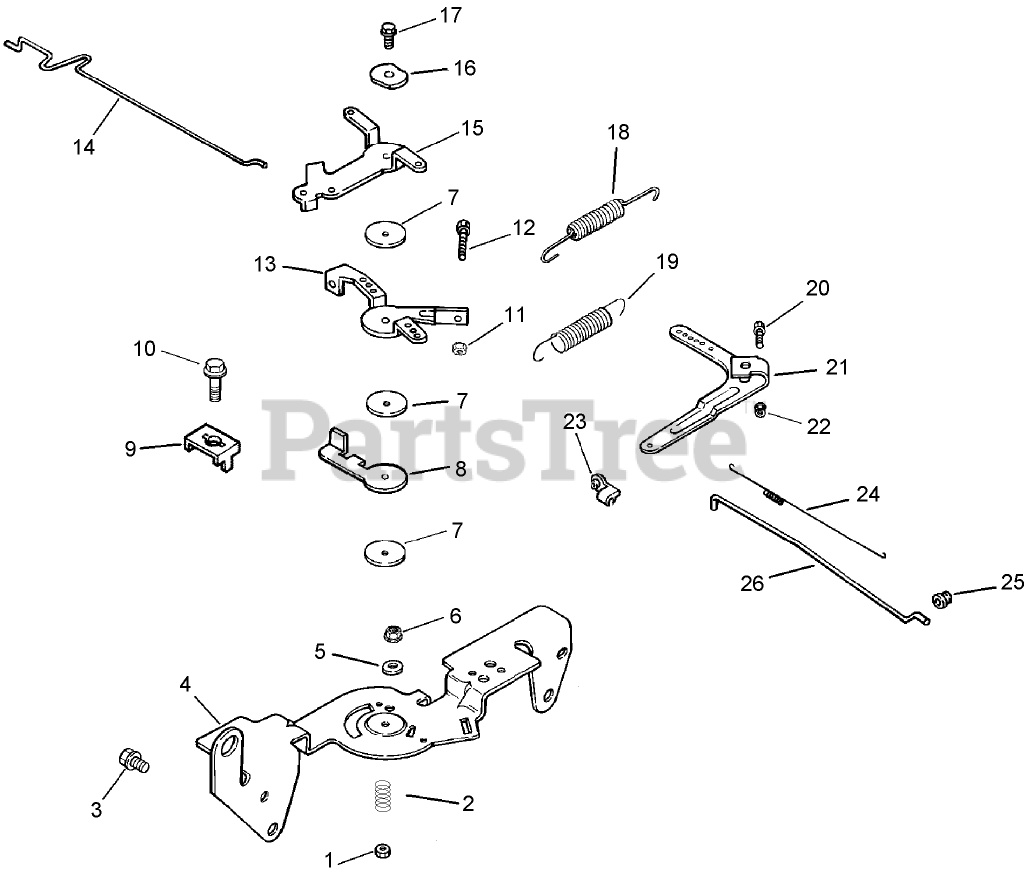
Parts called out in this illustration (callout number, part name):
1	NUT-LOCK (M5X.8)
2	SPRING-RETURN, CHOKE
3	SCREW-FLANGE, THREAD FORMING (M6X1.0X16)
4	Bracket-Control
5	Washer-Lock (.25)
6	Nut-HF (M5x0.8)
7	WASHER-FLAT (5.5MM)
8	Lever-Actuator, Throttle
9	CLAMP-CABLE
10	SCREW-FLANGE, THREAD FORMING (M5X0.8X16)
11	NUT (M4X0.7)
12	Screw (M4x0.7x30)
13	Lever-Control, Throttle
14	Linkage-Choke
15	LEVER-CHOKE
16	WASHER-SPRING (1/4)
17	SCREW-FLANGE, THREAD FORMING (M5X.8X20)
18	Spring-Limiter, Throttle
19	Spring-Governor
20	BOLT-SQ NECK, RD HD (M6X1.0X25)
21	Lever-Governor
22	NUT-FLANGE (M6X1.0)
23	BUSHING-RETAINING, LINKAGE
24	SPRING-LINKAGE
25	BUSHING-LINKAGE, THROTTLE
26	Linkage-Throttle
